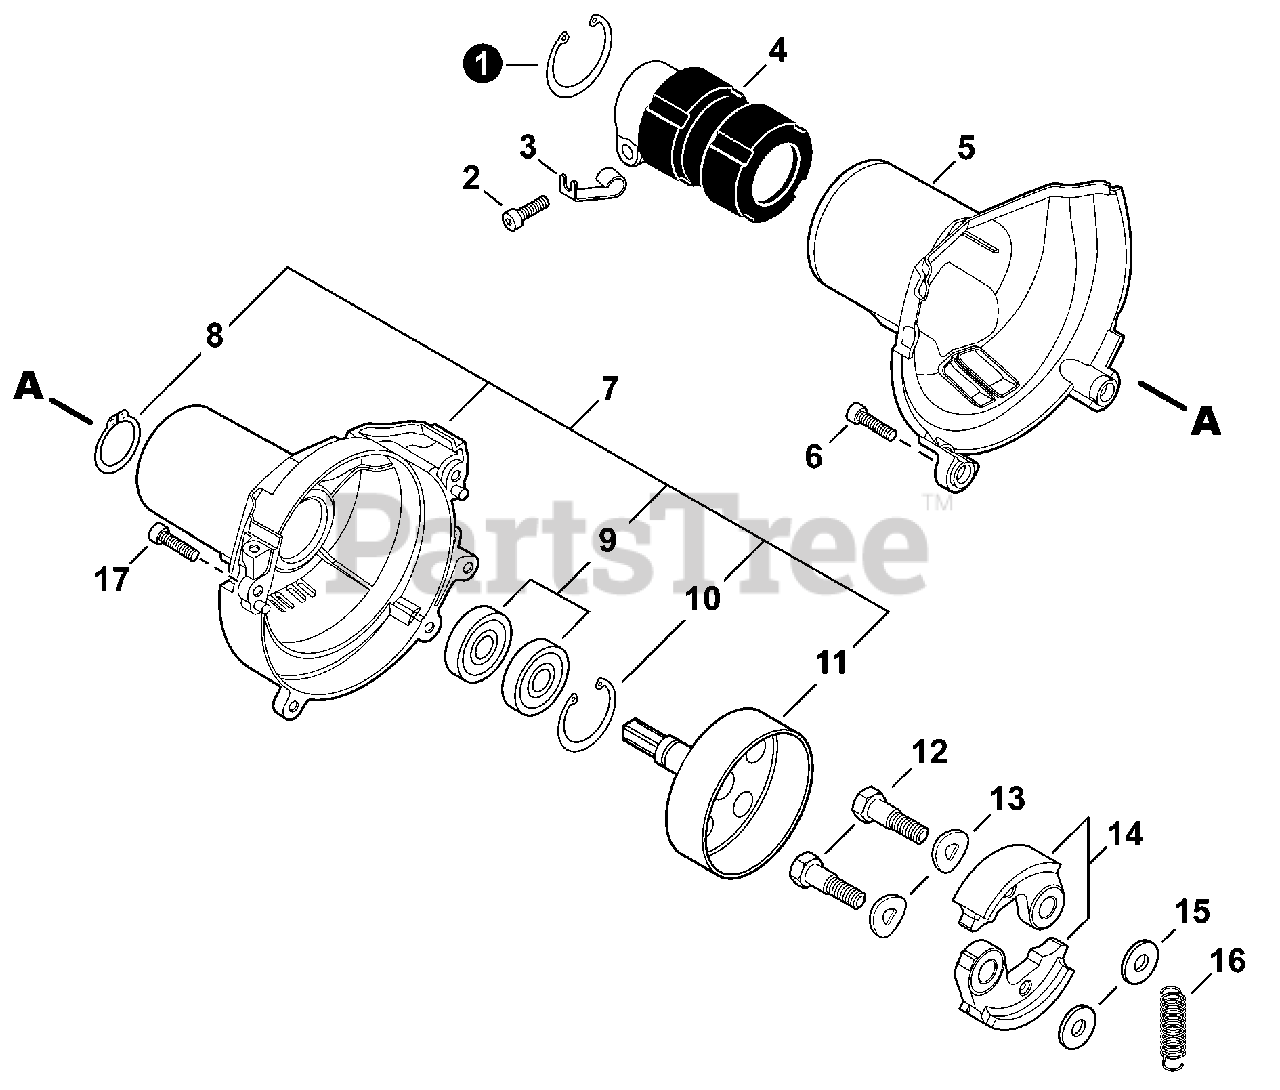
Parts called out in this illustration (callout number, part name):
1	RING, SNAP Ø42
2	BOLT, TORX 5×25
3	CLIP, CABLE
4	HOLDER, MAIN PIPE
5	PROTECTOR, FAN COVER
6	BOLT, TORX 5×20
7	COVER ASSY, FAN
8	RING, SNAP 12
9	BEARING, BALL 6001
10	RING, SNAP 28
11	DRUM, CLUTCH
12	BOLT, CLUTCH 8×7.9×M6
13	WASHER 8.5×16×0.5
14	SHOE, CLUTCH
15	WASHER 6.2×19×1.0
16	SPRING, CLUTCH
17	BOLT, TORX 5×16
